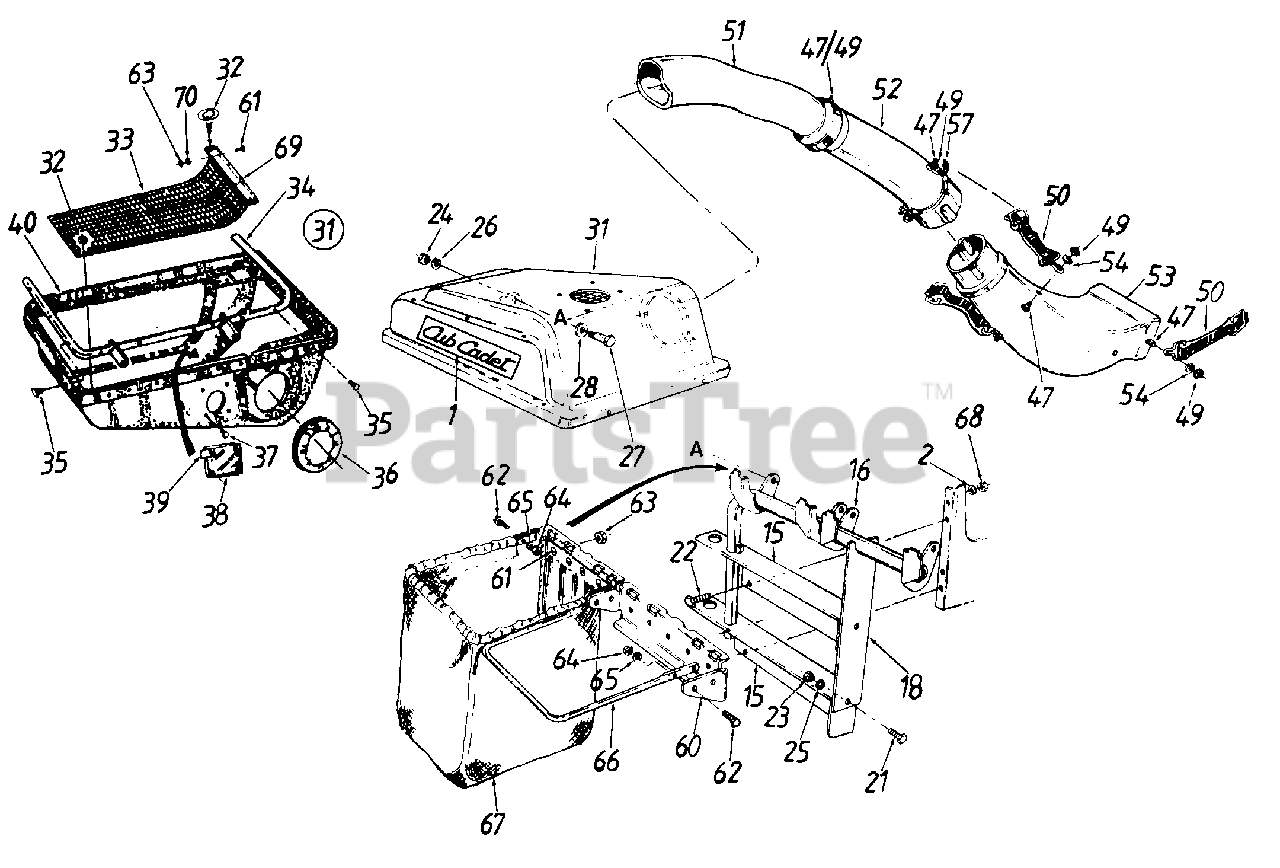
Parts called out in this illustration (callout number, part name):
1	Cub Cadet Name Plate
2	Fl.-Wash. 1/4" I.D.*
15	Catcher Support Tube Mtg. Brkt.
16	Catcher Support Tube Ass'y.
18	Catcher Latch and Support Brkt.
21	Hex Bolt 5/16-18 x .75"*
22	Hex Bolt 1/4-20 x .62" Lg. Grade 5
23	Hex Nut 5/16-18 Thd.*
24	Hex Nut 3/8-16 Thd.*
25	L.-Wash. 5/16" I.D.*
26	L.-Wash. 3/8" I.D.*
27	Shld. Bolt 3/8-16 x . 500" Dia.
28	Bell.-Wash. .505" I.D.
31	Grass Catcher Cover Ass'y.
32	Twist Fastener
35	Hex Tap Scr. 1/4-20 x .5"
36	Seal
37	Truss Mach. B-Tap Scr. #10 x .5" Lg.
38	Plastic Plate
39	Speed Nut
40	Grass Catcher Cover
47	Hex Bolt 1/4-20 x .50"*
49	Hex Ins. L-Nut 1/4-20 Thd.
50	Retainer Strap Ass'y.
51	Catcher Elbow
52	Catcher Tube
53	Discharge Chute
54	L.-Wash. .270" I.D.
57	Retainer Hook Brkt.
61	Truss Mach. Scr. #10-24 x .50" Lg.
62	Hex Bolt 1/4-28 x .75"
63	Hex Sems Nut #10-24 Thd.
64	Hex Nut 1/4-28 Thd.*
65	L.-Wash. 1/4" I.D.*
67	Grass Catcher Bag
68	Hex L. Nut 1/4-20 Thd.*
69	Screen Mtg. Brkt.
70	Flat Wash. 114" I.D.
